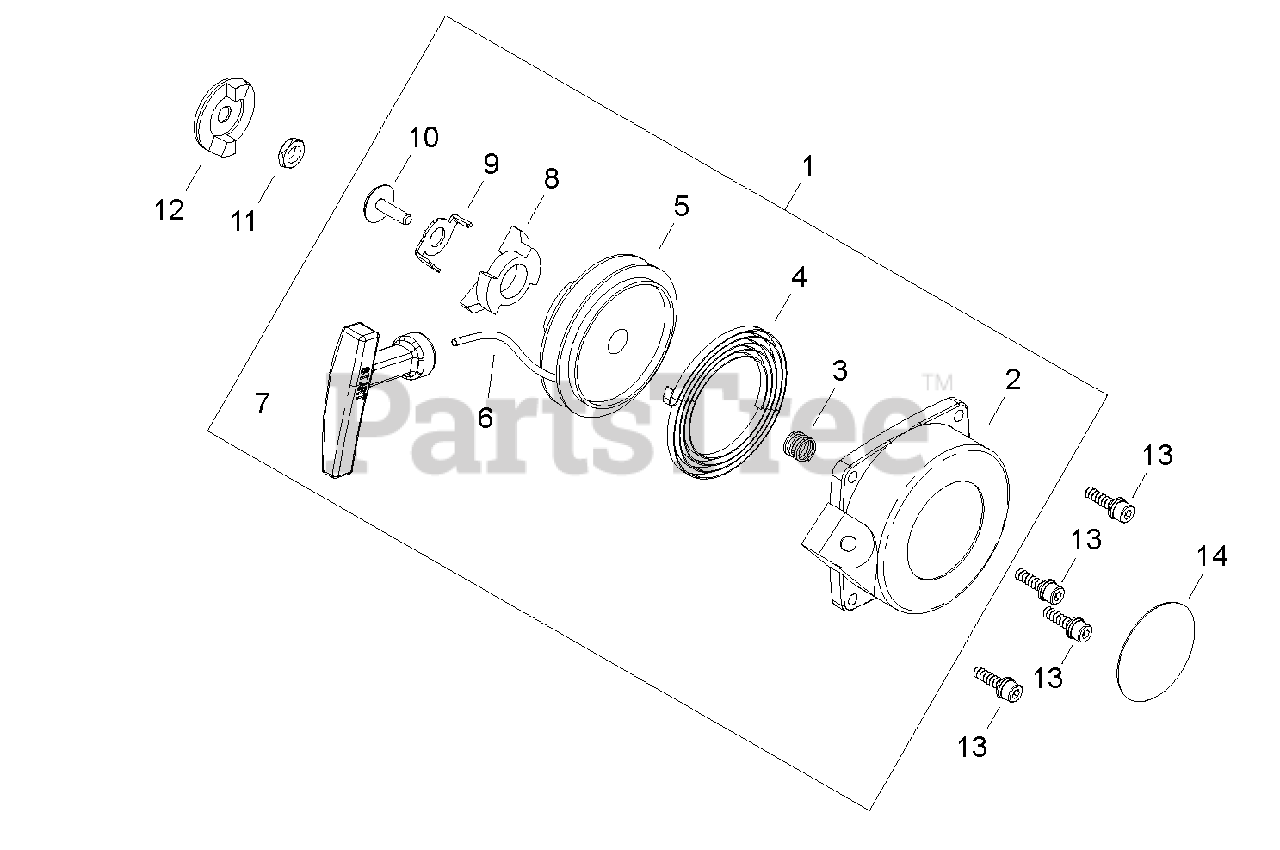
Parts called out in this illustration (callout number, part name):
1	STARTER ASSY, RECOIL
2	CASE, RECOIL STARTER
3	SPRING, PAWL
4	SPRING, RECOIL
5	REEL, ROPE
6	ROPE, STARTER
7	GRIP, STARTER
8	PAWL, STARTER
9	RETAINER
10	SCREW
11	NUT M8×1
12	PULLEY, STARTER
13	BOLT M5×20
14	LABEL, RECOIL C4
